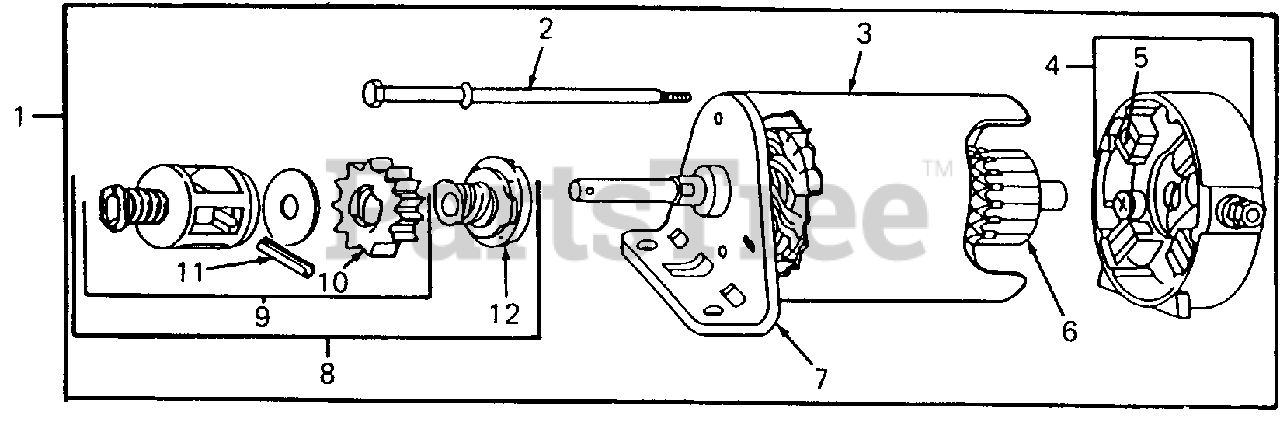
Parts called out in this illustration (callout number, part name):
1	Motor & Drive Assy
3	Housing Assy
4	End Cap Assy
5	Brush Assy
6	Armature Assy
7	End Cap Assy
8	Drive Assy
9	Retainer Kit
10	Gear
11	Pin, Roll
12	Clutch Assy
